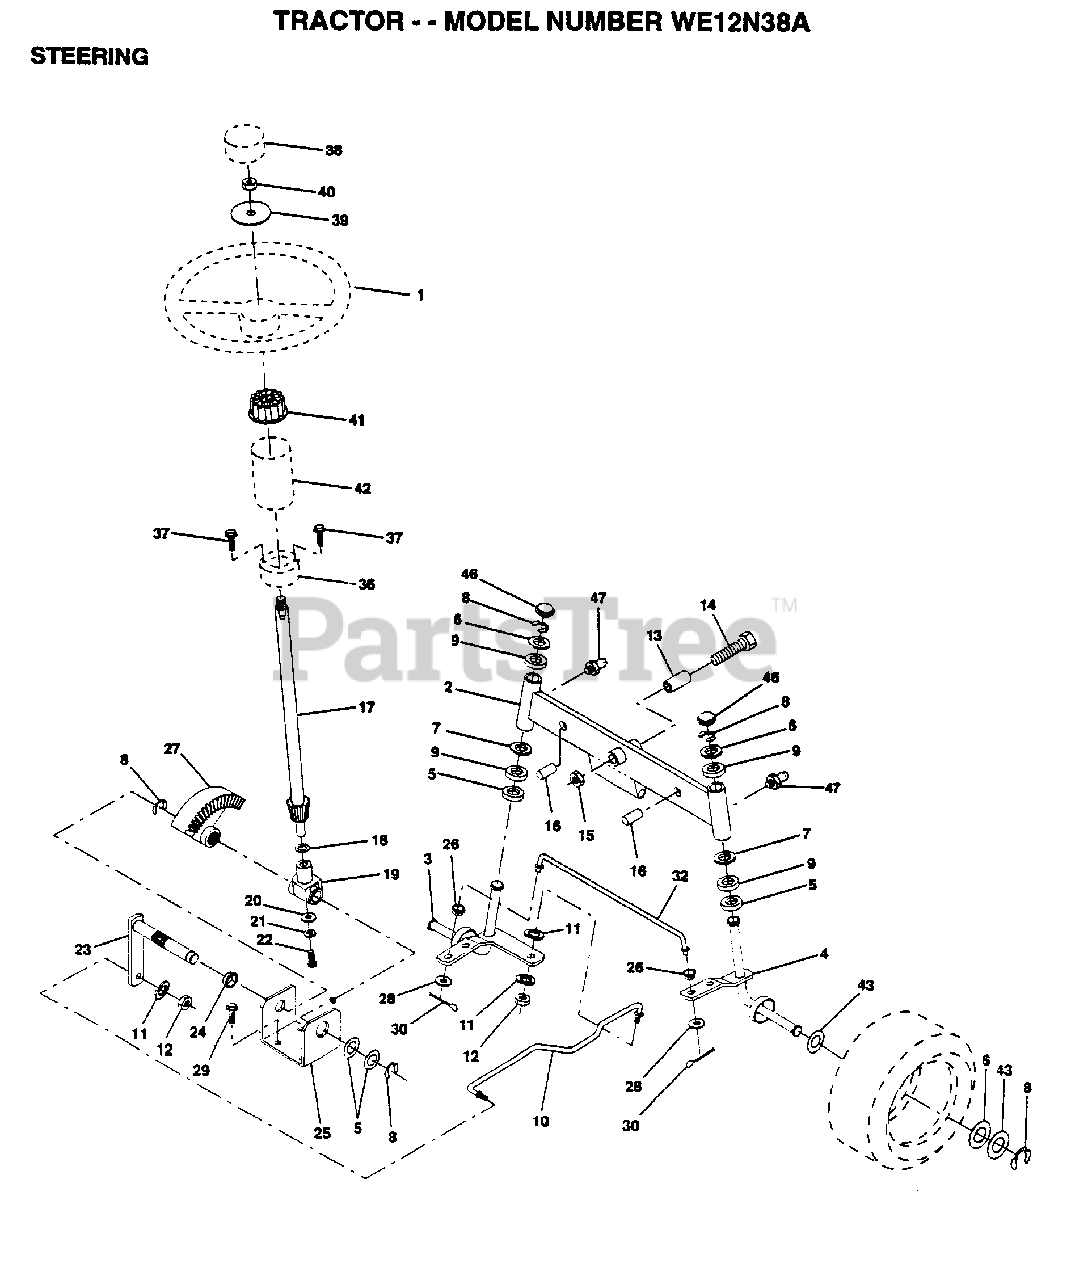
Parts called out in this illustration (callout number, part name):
2	AXLE ASM FRONT
3	SPINDLE LH
4	SPINDLE RH
5	WASHER .T
6	WASHER
7	WASHER
8	RING
9	COL. SRTG. BEAR.
11	LOCKWASHER
13	BEARING
14	BOLT HEX 5/8-11
15	"NUT-LOC,FLANGE LT"
16	AXLE PIN
17	SHAFT ASM
18	THRUST WASHER
19	SUPPORT.SHAFT
21	LOCKWASHER
22	"SCREW,SPECIAL"
24	NYLINER T
25	"BRKT,STEERING"
26	BUSHING.DRAGLINK
27	GEAR SECTOR
28	WASHER
29	SCREW
30	COTTER PIN
32	TIE ROD
38	ST WHL INSERT CAP
39	WASHER T
40	GRIPCO NUT
41	ADAPTER-WHEEL LT
42	"TUBE, STR SHAFT"
43	WASHER
46	CAP
47	ZERK M
